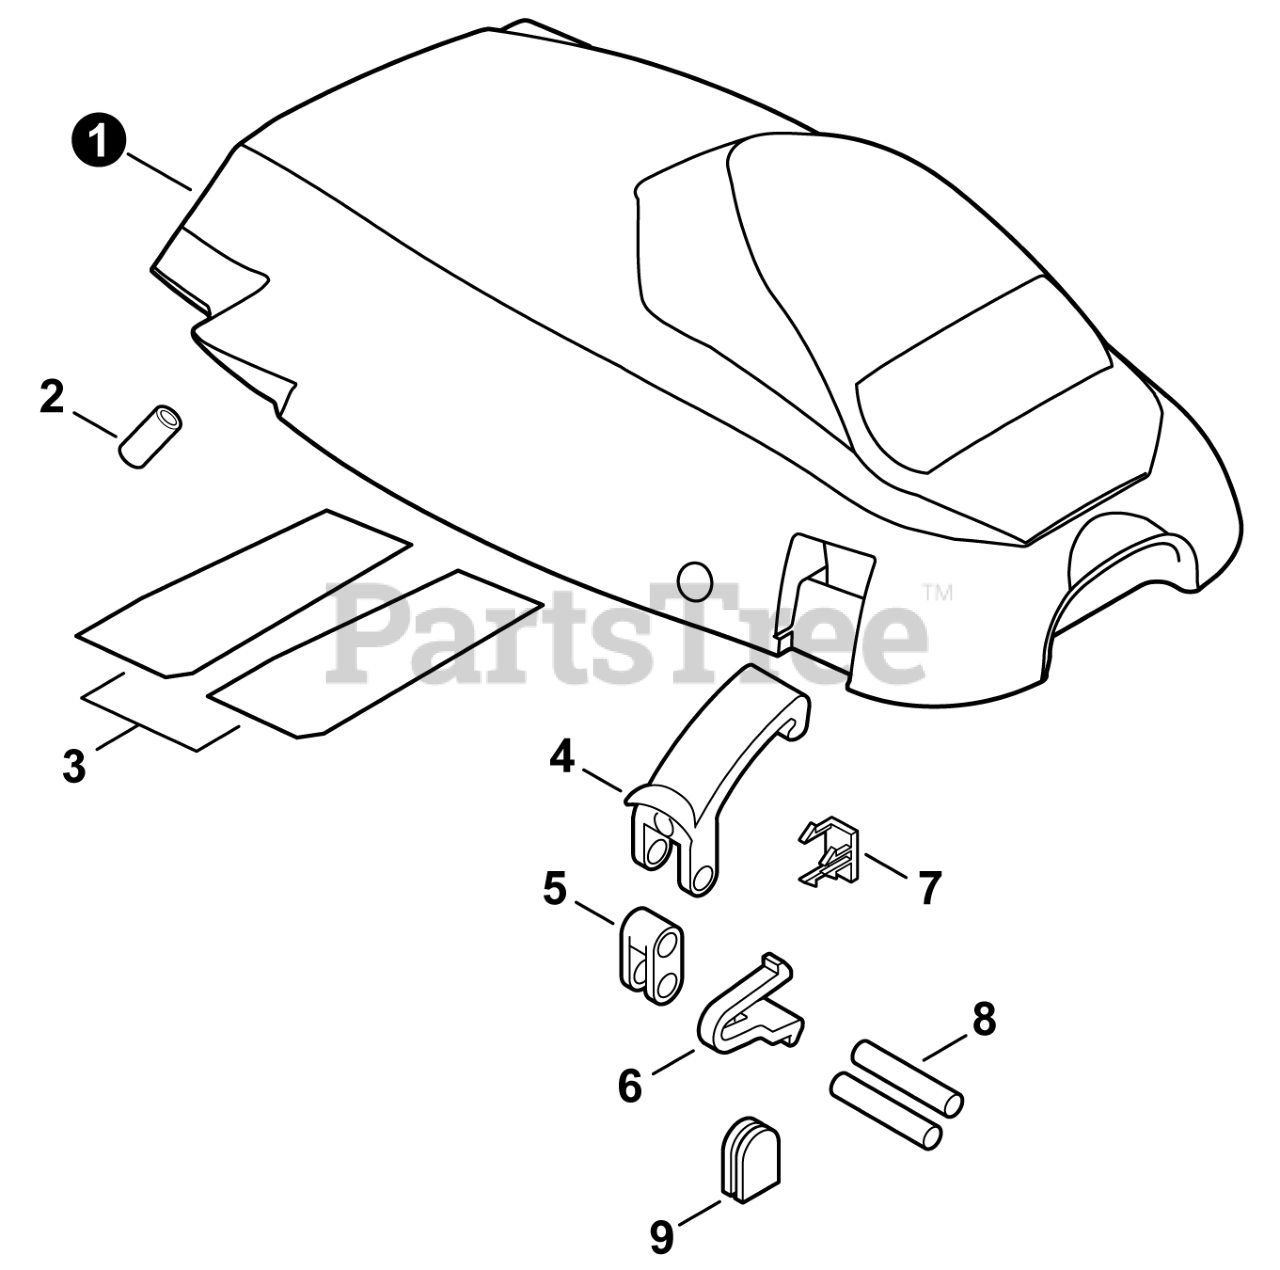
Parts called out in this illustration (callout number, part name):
1	COVER, ENGINE
2	BUSHING 3×7×10
3	SHIELD, HEAT
4	LATCH, ENGINE COVER
7	STOPPER
8	PIN 4×17.8
